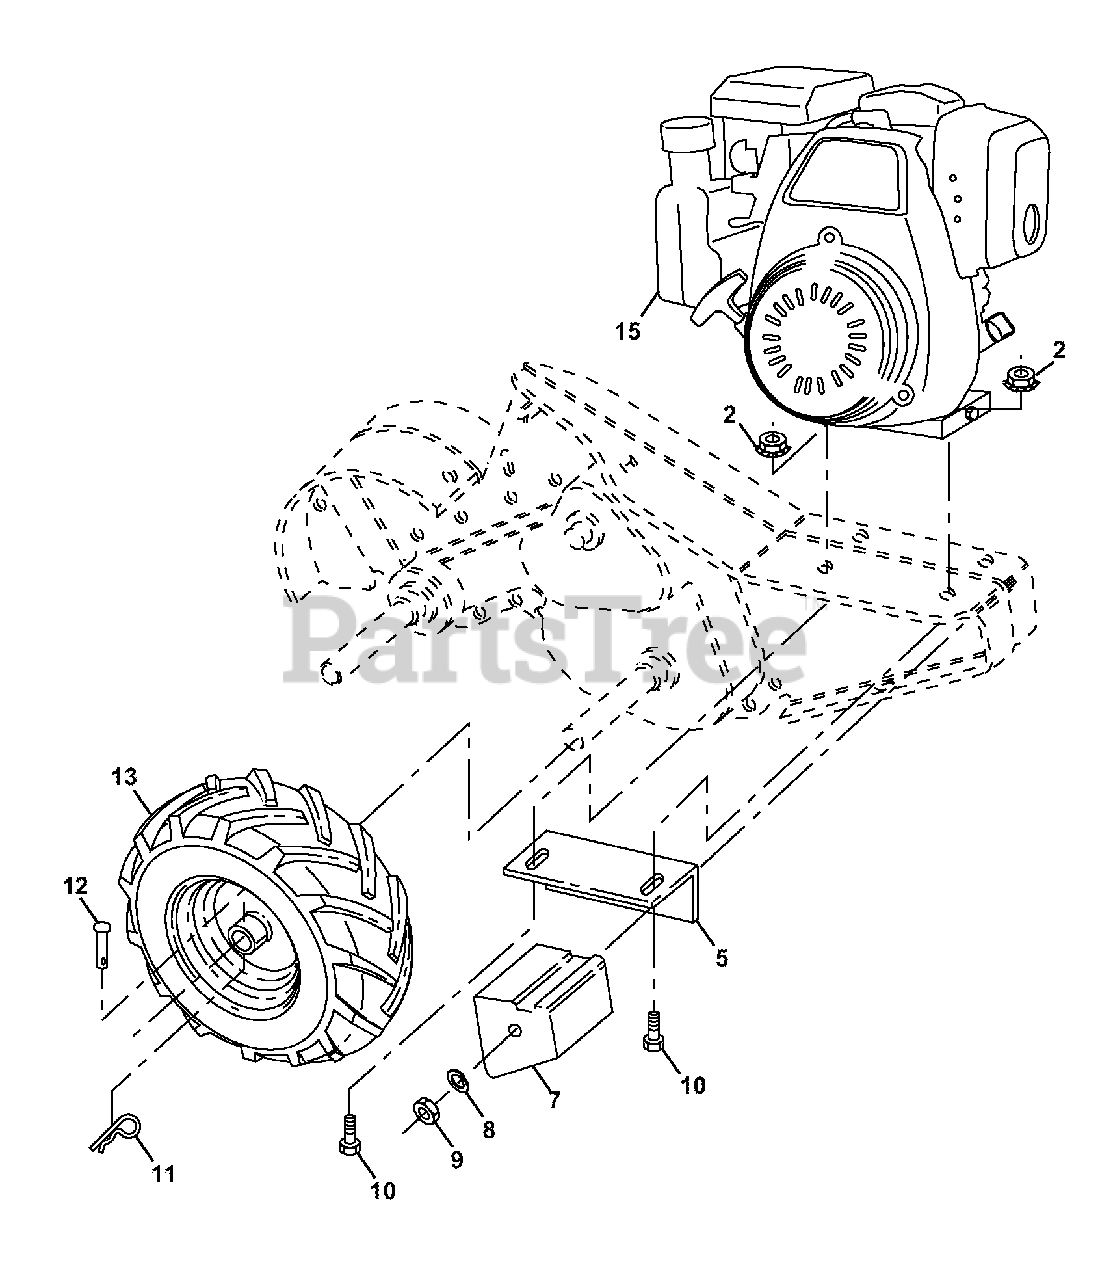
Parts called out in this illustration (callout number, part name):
2	Locknut, Hex, Flange 5/16-18
5	Bracket, Reinforcement
7	Counter Weight, R.H.
8	Washer, Lock 3/8
9	Nut, Hex 3/8-16
10	Bolt, Hex 5/16-18 x 1-1/2
11	Clip, Hairpin
12	Rivet, Drilled
13	Tire
13	Rim
13	Tire Valve
